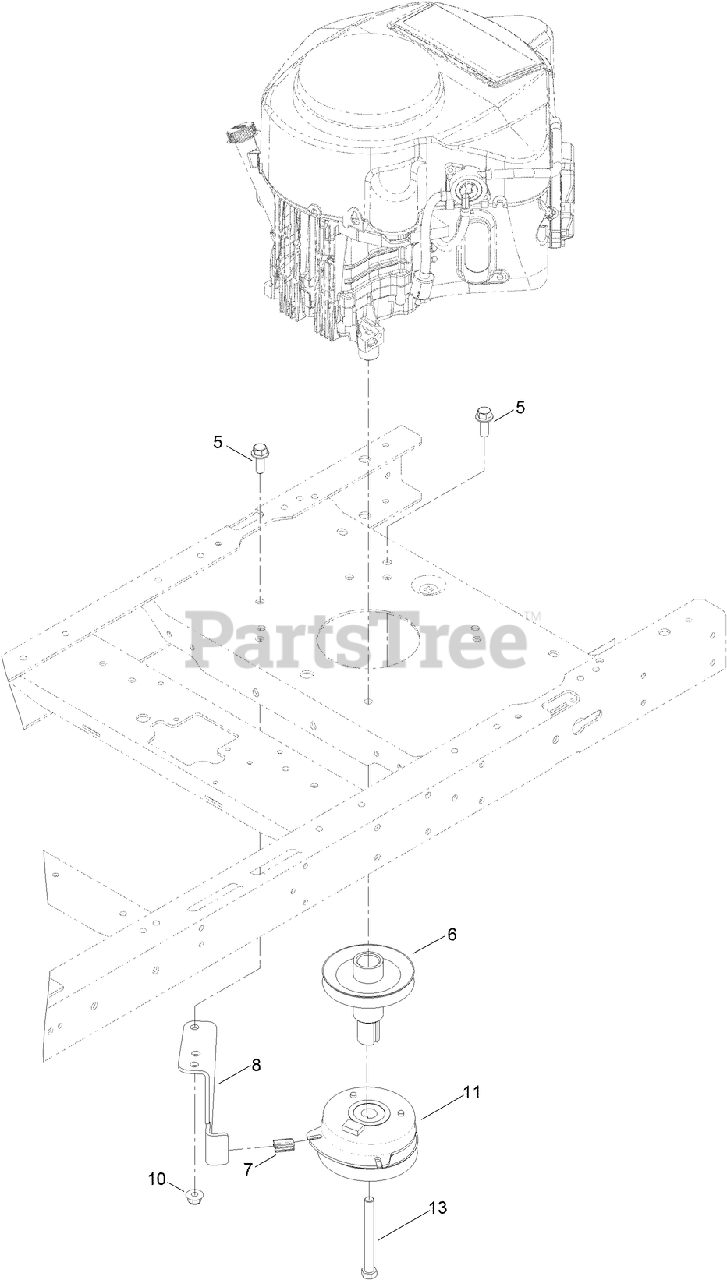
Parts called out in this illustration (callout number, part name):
5	SCREW-HHF
6	PULLEY-ENGINE
7	ISOLATOR-CLUTCH
8	STOP-CLUTCH
10	NUT-HF, NI
11	CLUTCH-PTO
13	SCREW-HH
